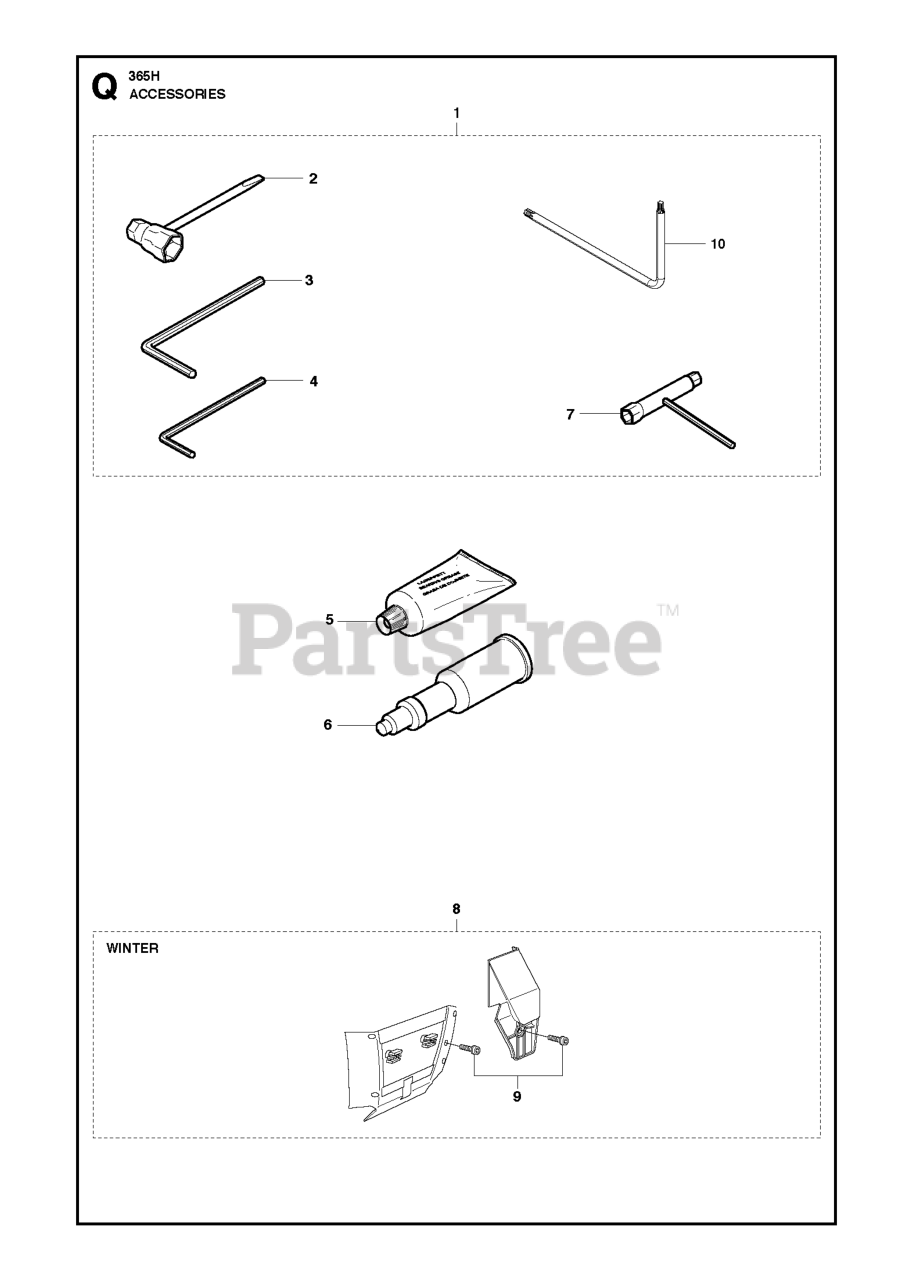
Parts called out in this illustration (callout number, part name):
2	COMBI TOOL
3	L-SPANNER
4	L-SPANNER
5	GREASE
6	Grease Gun
7	COMB.TOOL 8-10-14
8	WINTER KIT
10	WRENCH
